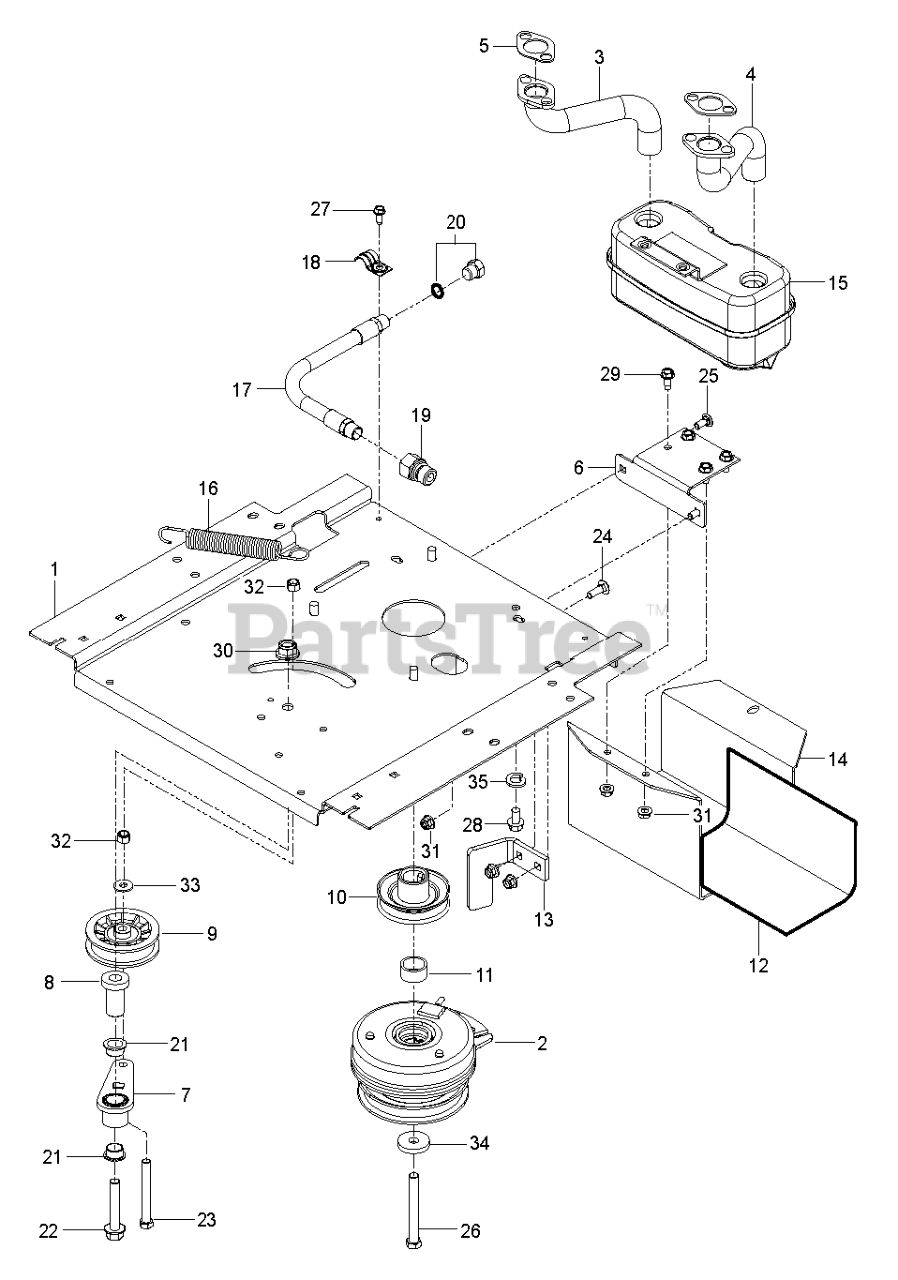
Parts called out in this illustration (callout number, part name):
1	PLATE.ENGINE.PNT.23"FRAME.EDIP
2	CLUTCH.105.FT-LBS
3	TUBE.EXHAUST.RH.FR961/FR730
4	TUBE.EXHAUST.LH.FR961/FR730
5	GASKET.EXHAUST.KAWASAKI
6	BRACKET MUFFLER MS431BLK
7	ARM IDLER
8	SPINDLE.IDLER
9	PULLEY, IDLER RAKE & ZTR
10	PULLEY.ENGINE
11	T & B SPACER
12	HEAT SHIELD
13	STOP, CLUTCH, BLACK
14	GUARD.MUFFLER.WO.TOW.HITCHX431
15	MUFFLER ASM TWIN
16	SPRING, DECK DRIVE
17	HOSE.ASSEMBLY.OIL.DRAIN
19	ADAPTER, OIL DRAIN
20	PLUG OIL DRAIN
21	BEARING.FLANGED.PLASTIC.3/4ID
22	BOLT.FLANGE.1/2-13 X 2.75.GRD5
23	HCS 3/8-16X3-1/2 TAPBLT GR5 ZD
24	RHSNB 5/16C X 1
25	BOLT 5/16C X 3/4" CARRIAGE
26	CLUTCH BOLT7/16-20X3.5 GR524HR
27	SCR 1/4-20X5/8 HEX SELF TAP ZD
28	BOLT
29	SCREW.THDROL.5/16-18X3/4.TTY
30	NUT, 1/2-13 HEX FLG NYLOC ZD
31	5/16-18 NYLOC FLANGE NUT
32	NUT 3/8-16 NYLOC
33	WASHER 5/16 FLAT
35	SLW 3/8 STD
